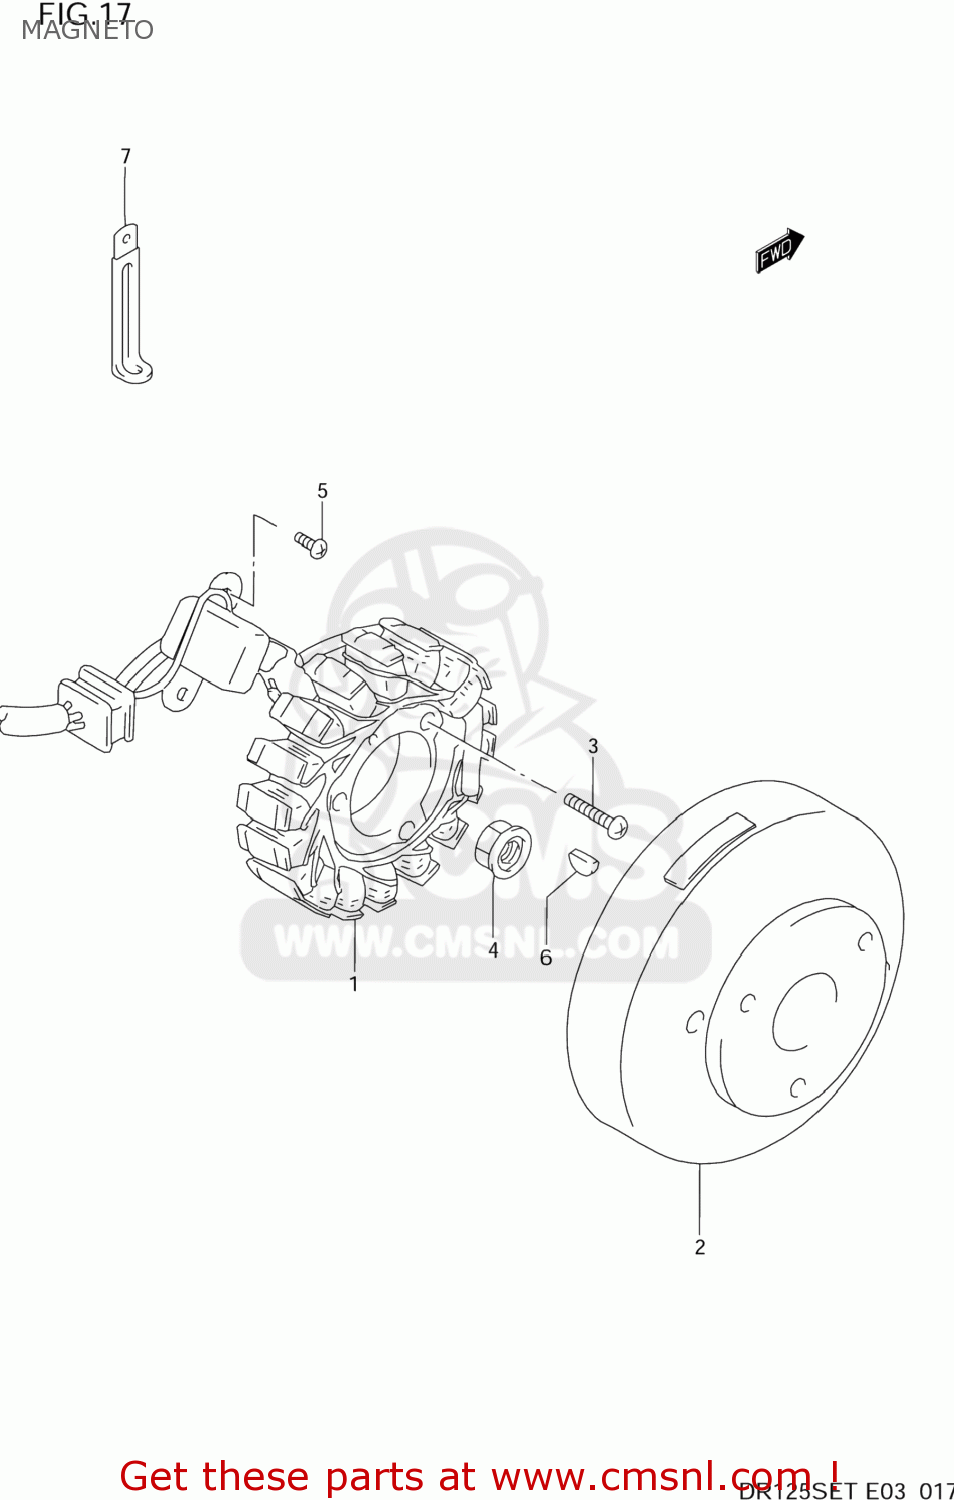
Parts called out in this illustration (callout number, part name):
1	STATOR ASSEMBLY
2	ROTOR ASSEMBLY
3	SCREW
4	NUT
5	SCREW
6	KEY
7	CLAMP
